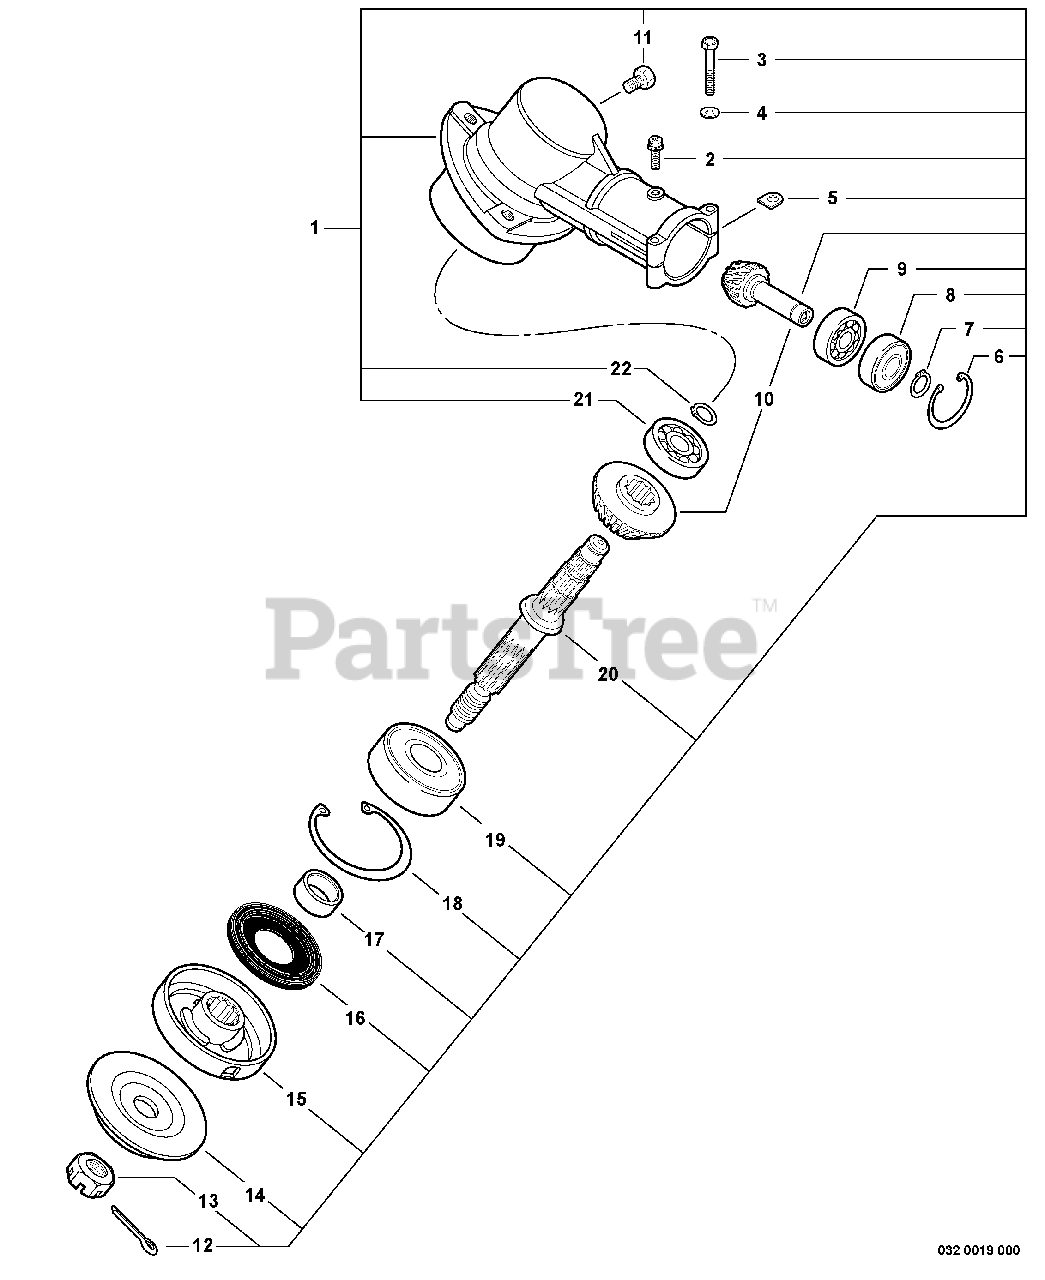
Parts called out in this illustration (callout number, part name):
1	GEAR CASE ASSY
2	SCREW - 5X10
3	BOLT - 5X40
4	WASHER - 5
6	RING, RETAINING - 28
7	RING, RETAINING - 12
8	BEARING, BALL - 6001
9	BEARING, BALL - 6001C3
10	GEAR SET - BEVEL
11	BOLT - 8X8
12	PIN, SPLIT - 2X22
13	NUT - 10 -- LEFT HAND
14	ADAPTOR, BLADE - LOWER
15	ADAPTOR, BLADE - UPPER
16	SEAL, OIL
18	RING, RETAINING - 32
19	BEARING, BALL - 6201
20	GEAR - SHAFT
21	BEARING, BALL - 6000
22	RING, RETAINING - 12
